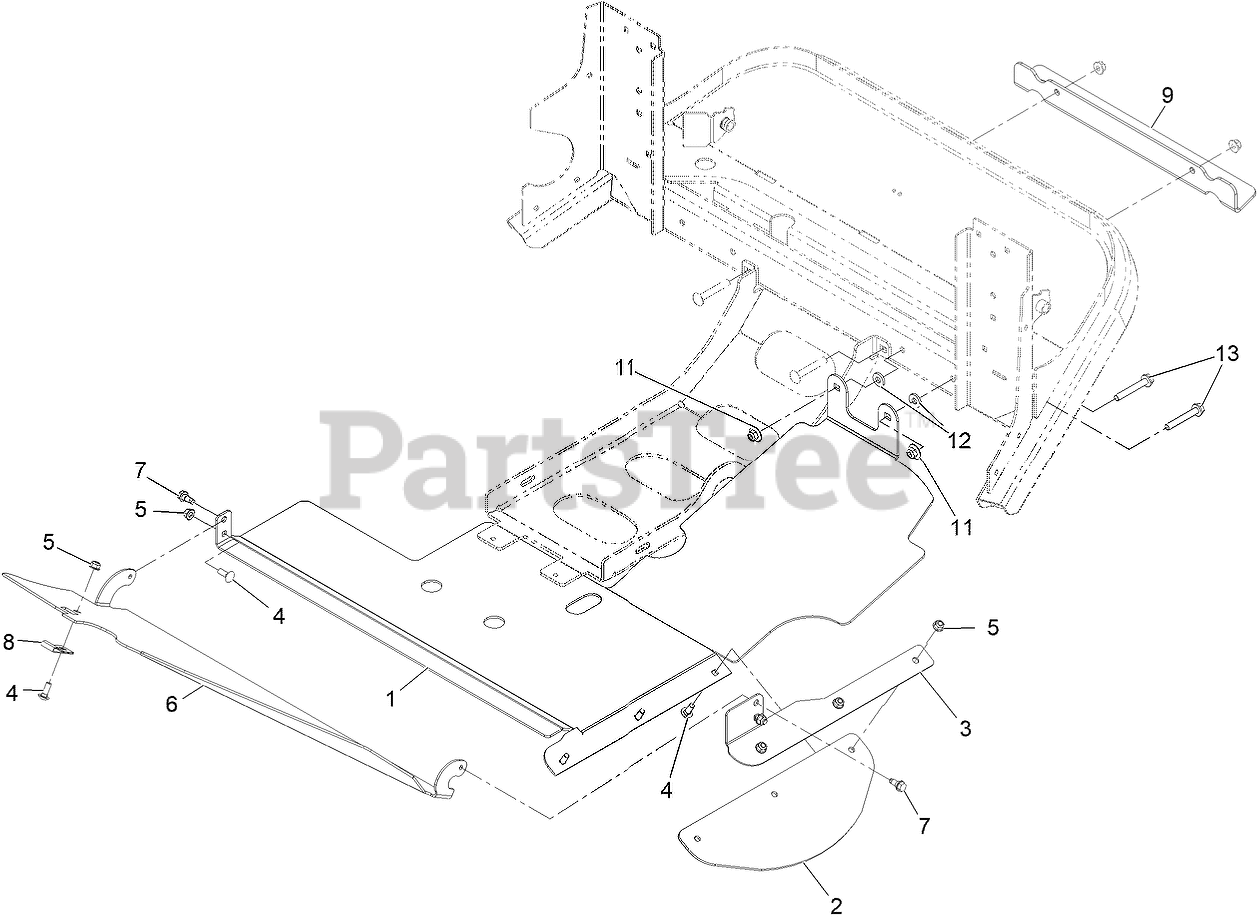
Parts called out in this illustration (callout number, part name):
1	PLATE-DISCHARGE
2	FLAP-RUBBER
3	BRACKET-FLAP, LH
4	SCREW-CARR
5	NUT-HF, NI
6	PANEL-DISCHARGE
7	SCREW-SHOULDER
8	BEARING-STRAP, NYLON
9	BRACKET-TIE DOWN
11	Nut-Nyloc 3/8-16 Flg
13	Screw-HHF
